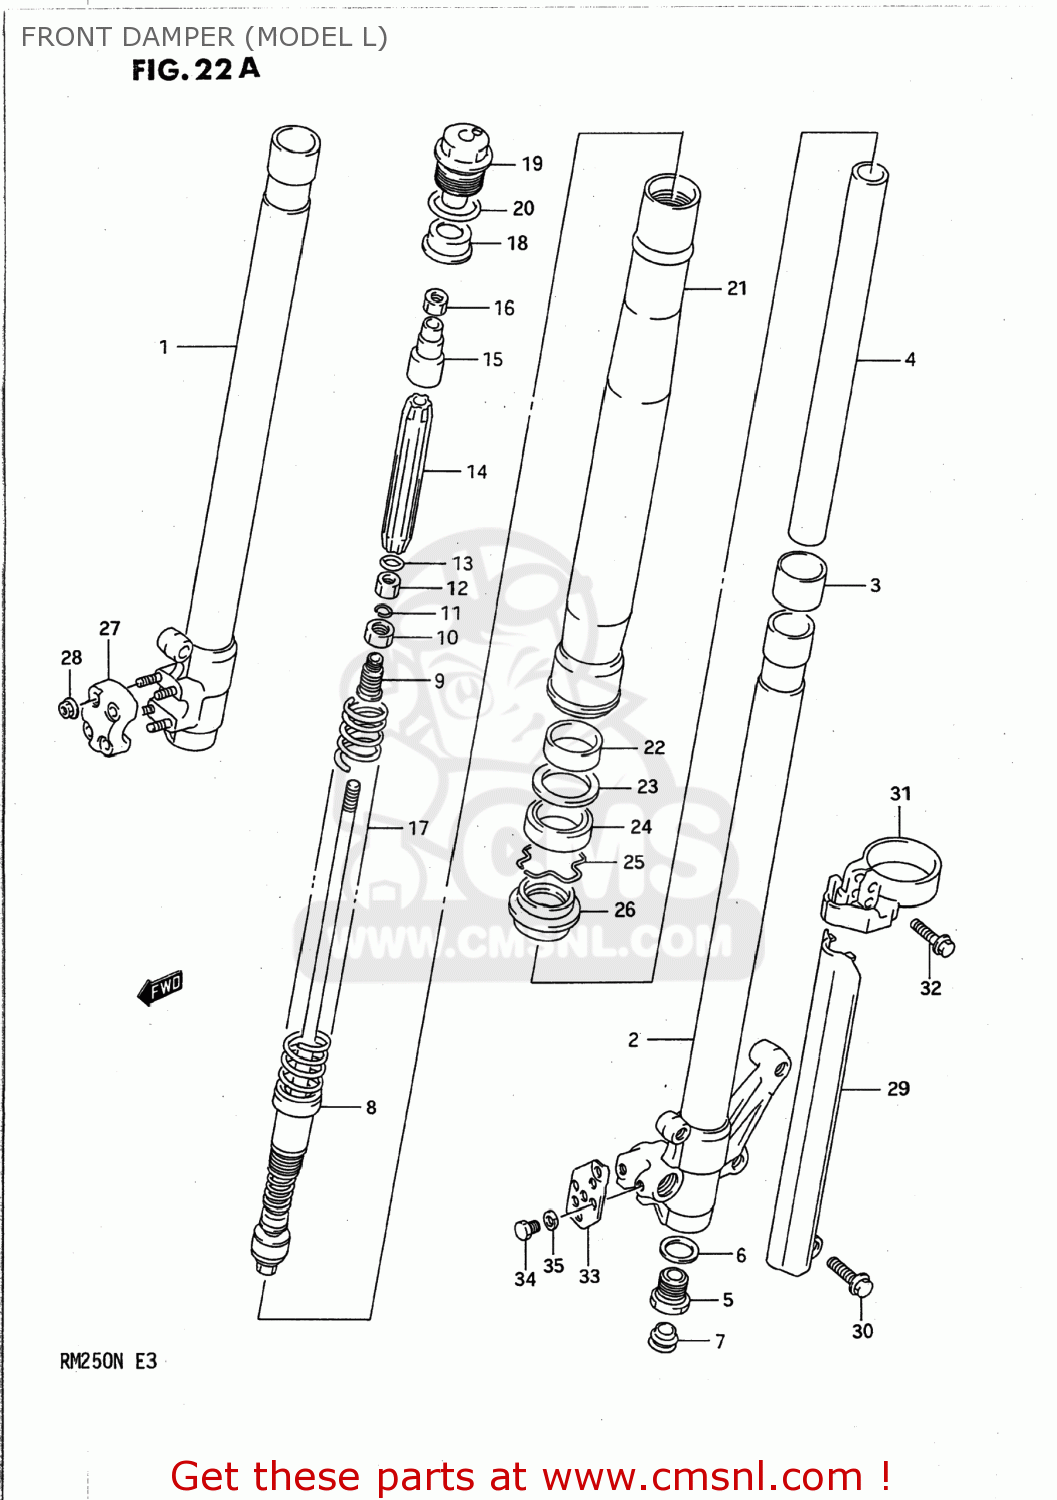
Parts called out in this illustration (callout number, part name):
1	TUBE,INNER,RIGHT
2	TUBE,INNER,LEFT
3	PISTON
4	CYLINDER
5	VALVE ASSEMBLY,BASE
6	GASKET (NAS)
7	CAP,RUBBER
8	ROD ASSY,PISTON
9	HOLDER,PIECE
10	PIECE,OIL LOCK
11	RING,SNAP
12	NUT,PIECE
13	O-RING
14	GUIDE,SPRING
15	SPACER,SPRING GUIDE
16	NUT
17	SPRING
18	GUIDE,SPRING WASHER
19	CAP,FORK
20	O RING
21	TUBE,OUTER
22	METAL,SLIDE
23	WASHER,FORK OIL SEAL
24	OIL SEAL,FRONT FORK
25	RING,OIL SEAL STOPPER
26	SEAL,DUST
27	HOLDER,AXLE
28	NUT
29	PROTECTOR,R
30	BOLT
31	GUIDE,PROTECTOR,R
32	BOLT, GUIDE
33	COVER,HOSE
34	BOLT 5X10
35	LOCK WASHER
